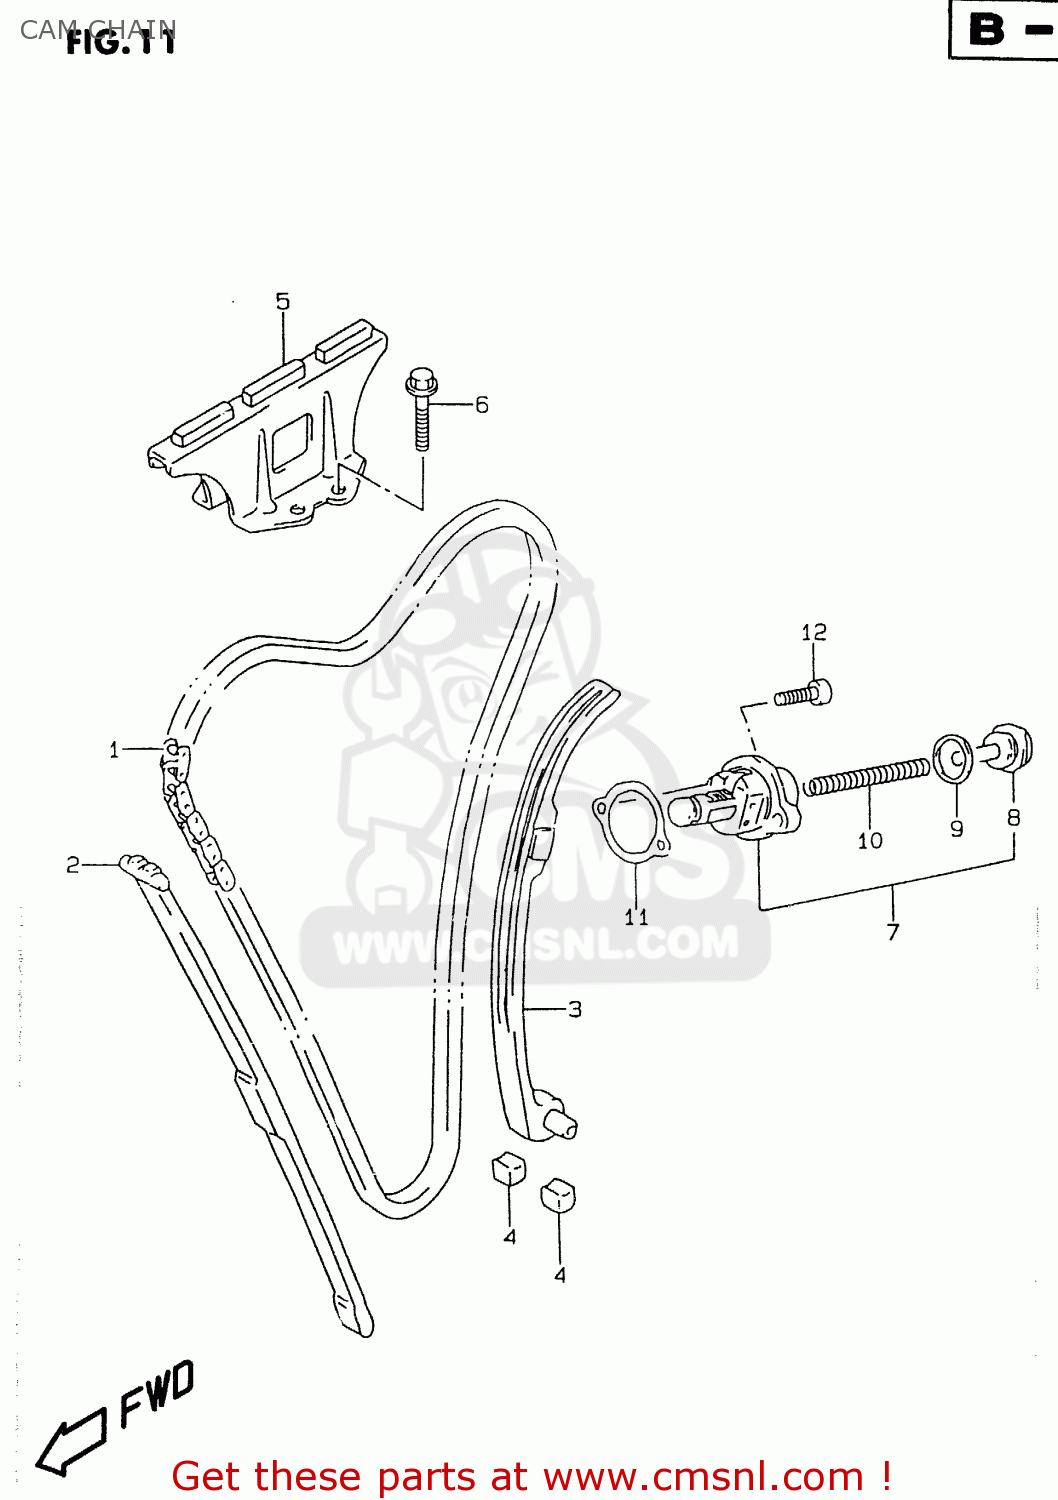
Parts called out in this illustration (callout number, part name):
1	CHAIN,CAMSHAFT DRIVE
2	GUIDE,CAM CHAIN NO.1
3	TENSIONER,CAM CHAIN
4	CUSHION,CAM CHAIN TENSIONER
5	GUIDE,CAM CHAIN NO.2
6	BOLT
7	ADJUSTER ASSY,TENSIONER
8	PLUG
9	GASKET (NAS)
10	SPRING
11	GASKET,TENSIONER ADJUSTER (NAS)
12	BOLT,CL.COVER
